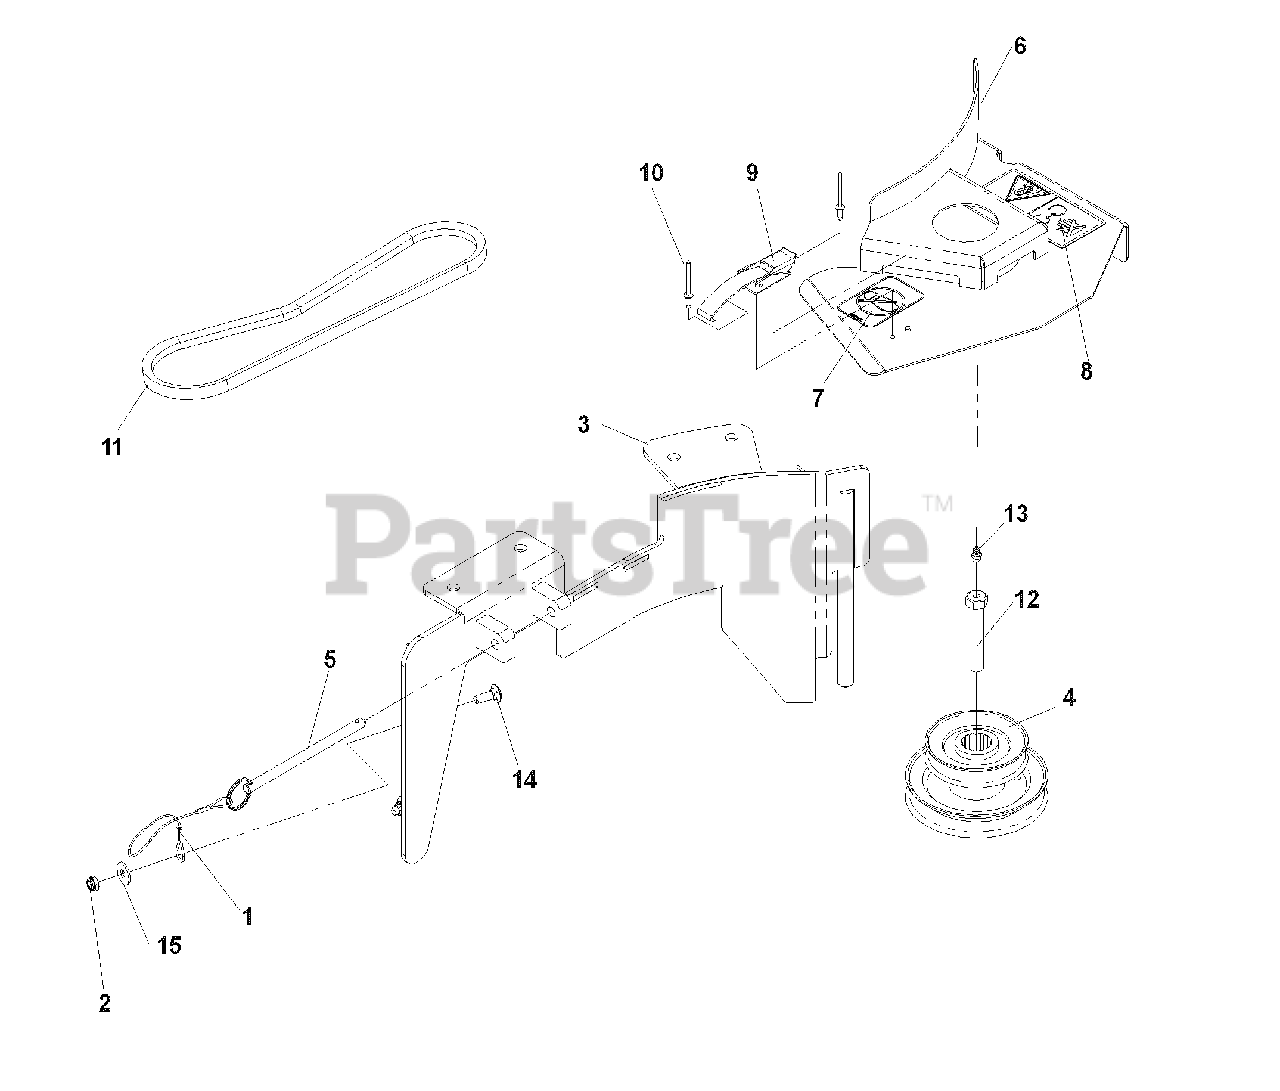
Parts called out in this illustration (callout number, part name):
2	NUT,1/4-20, THINNYLOC
3	BLOWERDECK PLATE, 42-48"DECKS
4	STACKED DOUBLE PULLEY, 42/48"DECKS
6	BELTSHIELD, 42"DECKS
7	DECAL, EURONOSTEP
8	DECAL, EURODANGERBELT
9	DRAW LATCH
11	BELT, 42"DECKS
12	HCS, 7/16-20x2 1/2, GR8
13	ZERK, STRAIGHT, 1/4-28
14	RHSNB, 1/4-20 x 3/4, GR2
15	WASHER, 1/4
